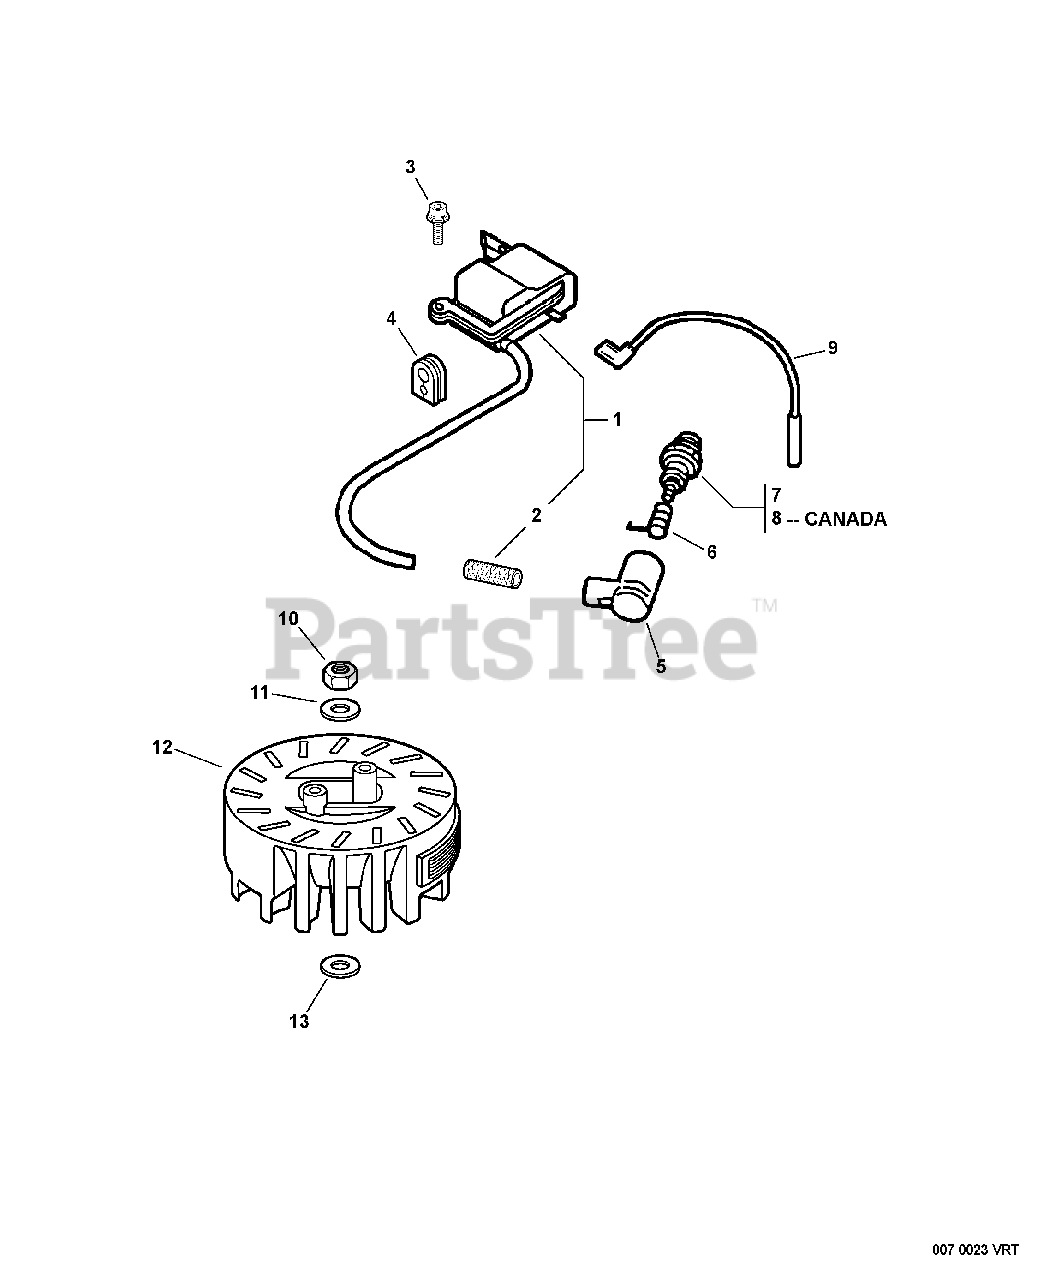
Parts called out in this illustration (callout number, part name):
1	COIL, IGNITION
2	TUBE, INSULATOR
3	BOLT 5×16
5	CAP, SPARK PLUG
6	TERMINAL, SPARK PLUG
7	SPARK PLUG - BPM8Y
8	SPARK PLUG - BPMR8Y
9	LEAD - GROUND
11	WASHER 8.5×16×1.2
12	FLYWHEEL
13	WASHER, CLUTCH
14	TUNE-UP KIT - REPOWER
15	TUNE-UP KIT - REPOWER
